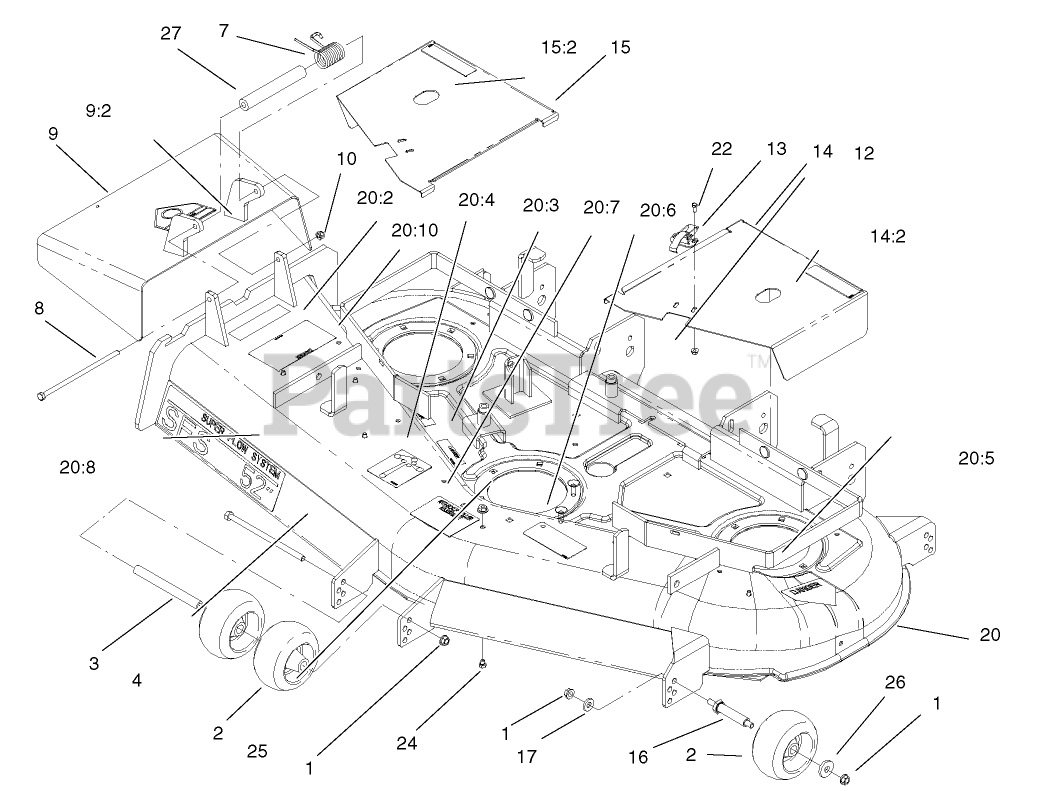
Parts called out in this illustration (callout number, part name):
1	NUT-HHF, WHIZ
2	WHEEL-GAGE
3	SPACER-WHEEL
4	SCREW-HH
7	SPRING-TORSION
8	SCREW-HH
9	Deflector ASM
9:2	DECAL-DANGER
10	NUT-LOCK, NI
12	NUT-LOCK, FLANGE
13	CLAMP-SLOTTED
14	LH COVER ASM
14:2	DECAL-DANGER
15	RH COVER ASM
15:2	DECAL-DANGER
16	SPACER
17	WASHER-BELLEVILLE
20	DECK SERVICE ASM (52, 100 SERIES)
20	Deck ASM W/ Decals
20:2	DECAL-WARNING
20:3	DECAL-COVER, MISSING
20:4	DECAL-ROUTING, BELT
20:5	DECAL-DANGER
20:6	DECAL-TORQUE, BLADE BOLT
20:7	DECAL-WHEEL, GAGE
20:8	DECAL
20:10	DECAL-DANGER, THROWN OBJECT
22	SCREW-HWH
24	SCREW-HH
25	NUT-HF
26	WASHER
27	SPACER
